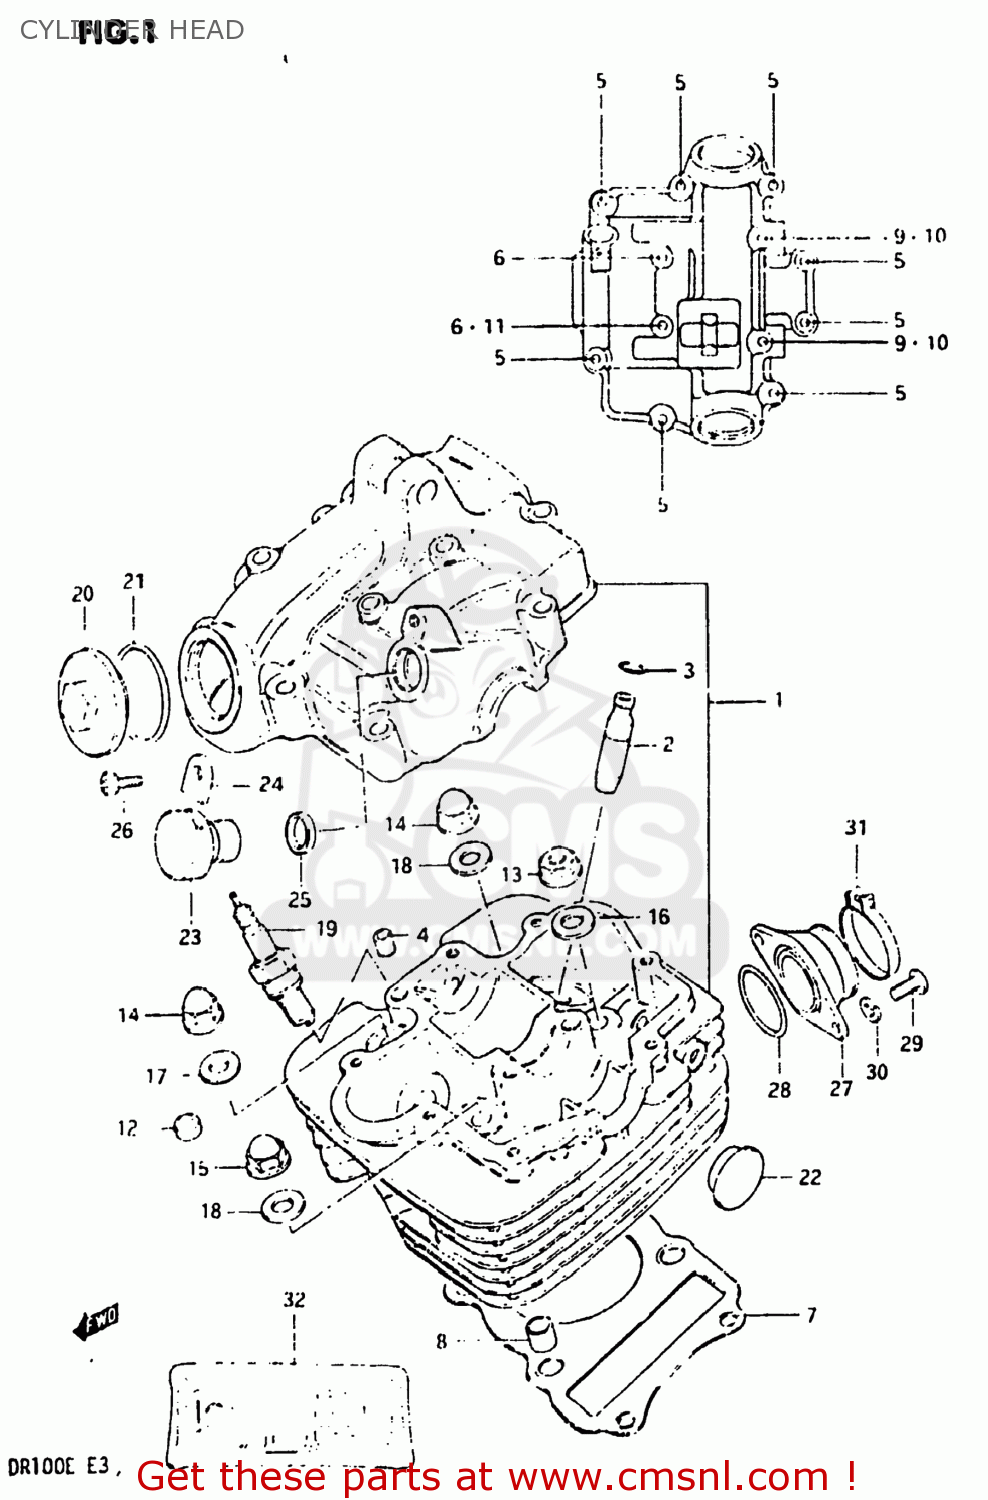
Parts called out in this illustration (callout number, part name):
1	HEAD ASSEMBLY,CYLINDER
2	GUIDE,VALVE
3	RING,SNAP
4	PIN(6.2X8X11)
5	BOLT
6	BOLT ,6X60
7	GASKET,CYLINDER HEAD
8	PIN
9	STUD 6X25
10	NUT
11	WASHER
12	PAD,CYLINDER HEAD
13	NUT
14	NUT (8MM)
15	NUT
16	WASHER(8.5X19X2.3)
17	WASHER (8.5X19X2.3)
18	GASKET (NAS)
19	SPARK PLUG D8EA
20	CAP,INSPECTION
21	O RING(D:3,ID:29.5)
22	PLUG(OD:22.5)
23	PLUG,TACH GEAR SLEEVE HOLE
24	PLATE,TACH DRIVE GEAR SLEEVE
25	SEAL,TACHOMETER DRIVEN
26	SCREW(5X12)
27	PIPE,INTAKE
28	O RING(D:2.4,ID:31.7)
29	SCREW
30	LOCK WASHER
31	CLAMP
32	GASKET SET
